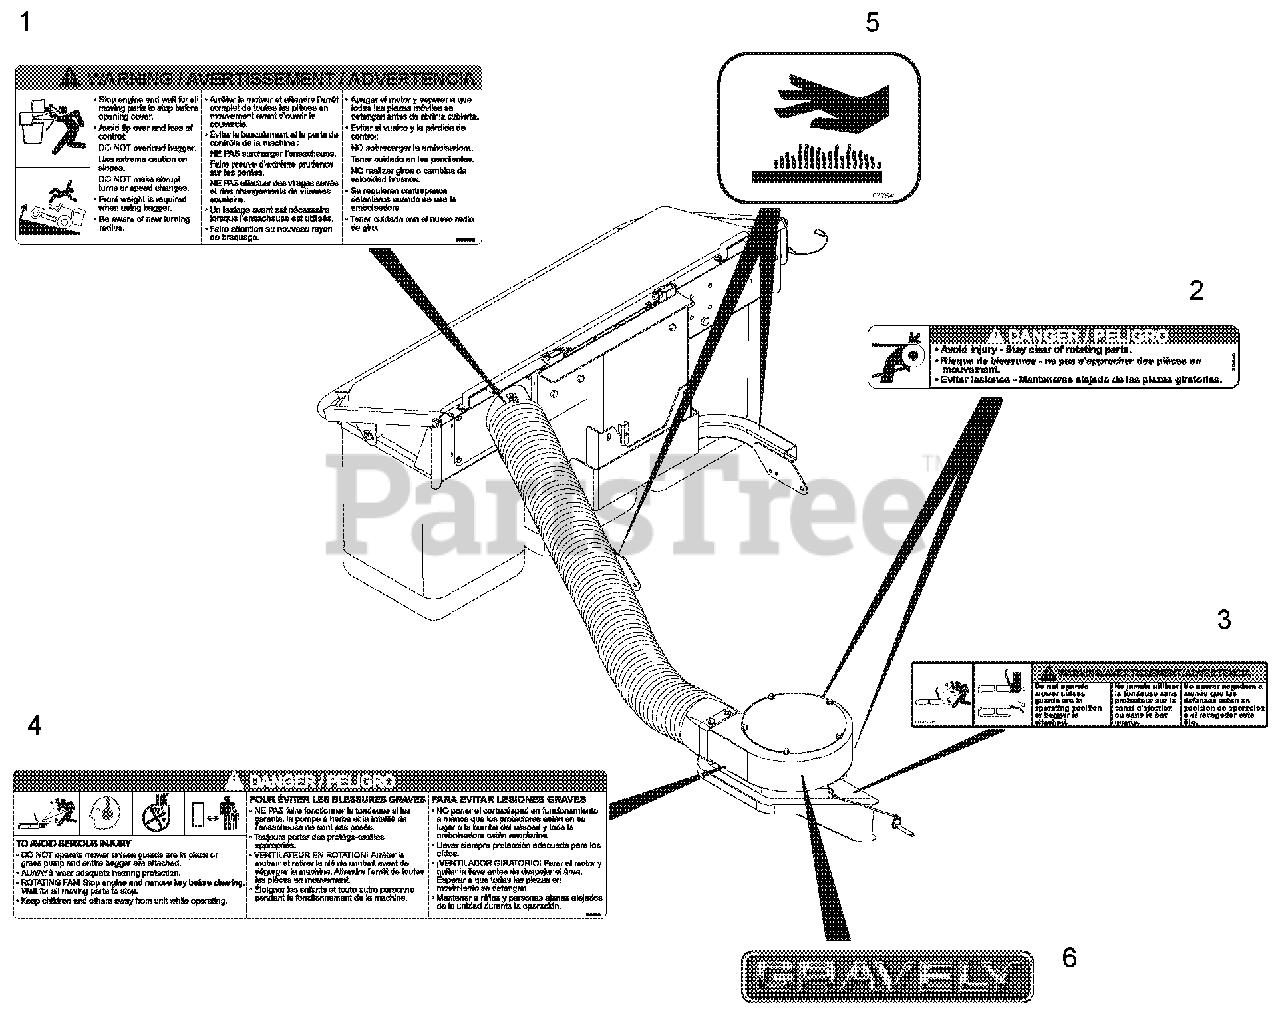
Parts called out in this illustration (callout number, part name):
1	Decal, Warning, Bagger Cover
2	Decal, Danger
3	Decal, Warning
4	Decal, Caution, Grass Pump
5	Decal, Hot Surface
6	Decal, Gravely
